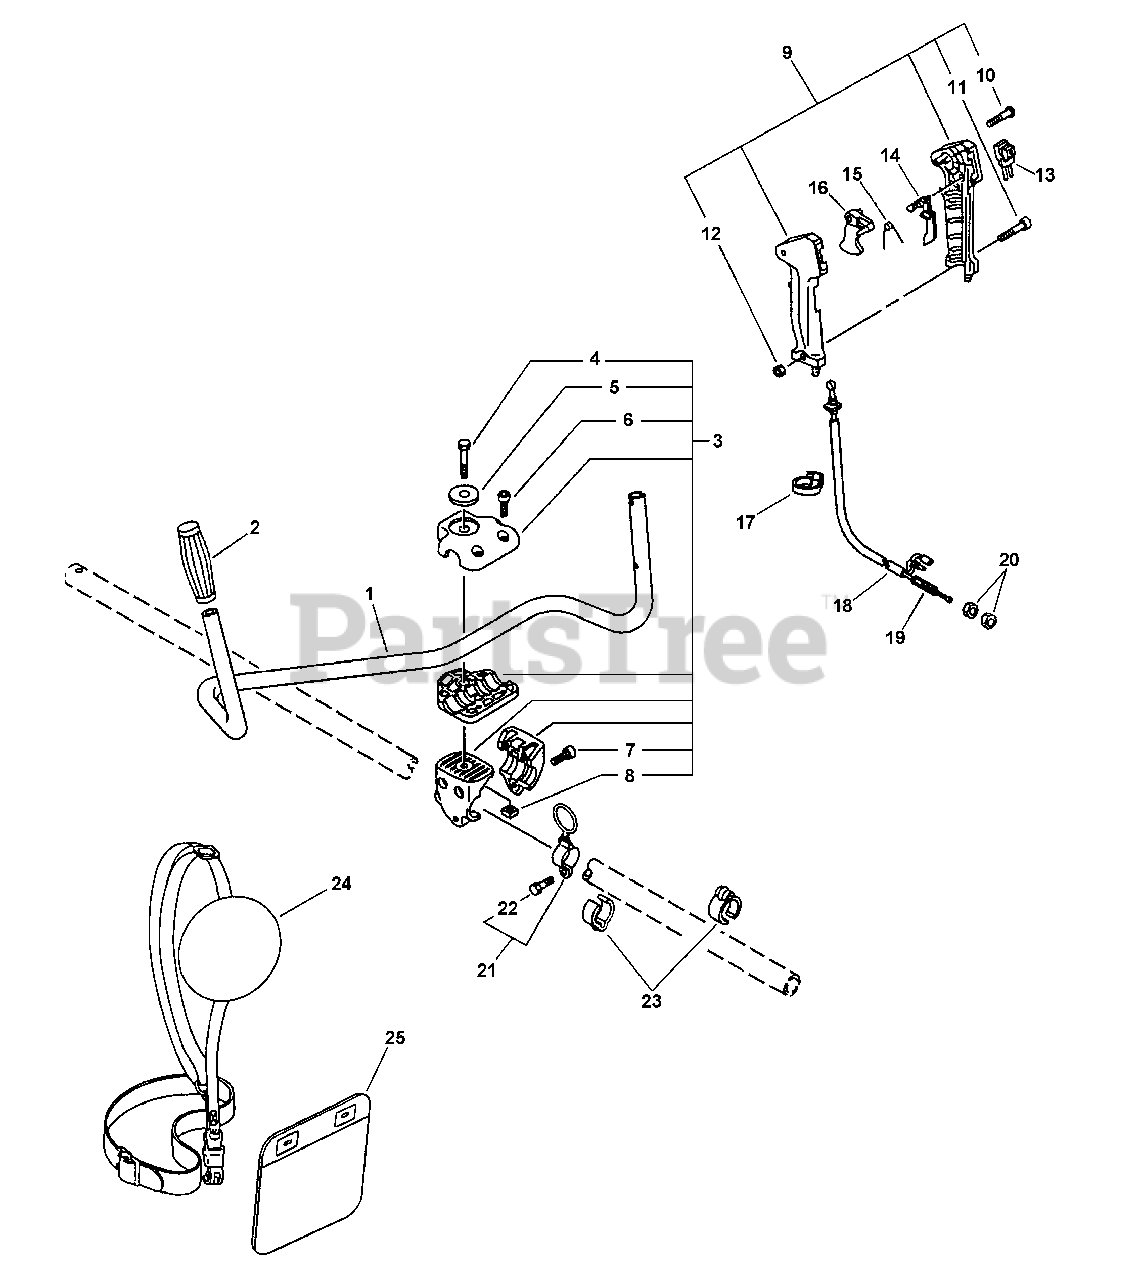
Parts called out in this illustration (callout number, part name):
1	HANDLEBAR
2	GRIP, HANDLE
3	BRACKET ASSY, HANDLE
4	BOLT 8×55
5	WASHER 8
6	BOLT 5×20
7	BOLT 5×30
8	NUT 8×1.25
9	CONTROL HANDLE KIT
10	SCREW 3×25
11	SCREW 5×30
12	NUT M5
13	IGNITION SWITCH ASSY
14	LOCKOUT, THROTTLE
15	SPRING, TORSION
16	TRIGGER, THROTTLE
17	CLIP
18	TUBE, FLEXIBLE 7×790
19	CABLE, THROTTLE
21	HANGER ASSY, HARNESS
22	BOLT 5×12
23	CLIP, CABLE 25 MM
24	SHOULDER STRAP ASSY
25	PAD, HIP
